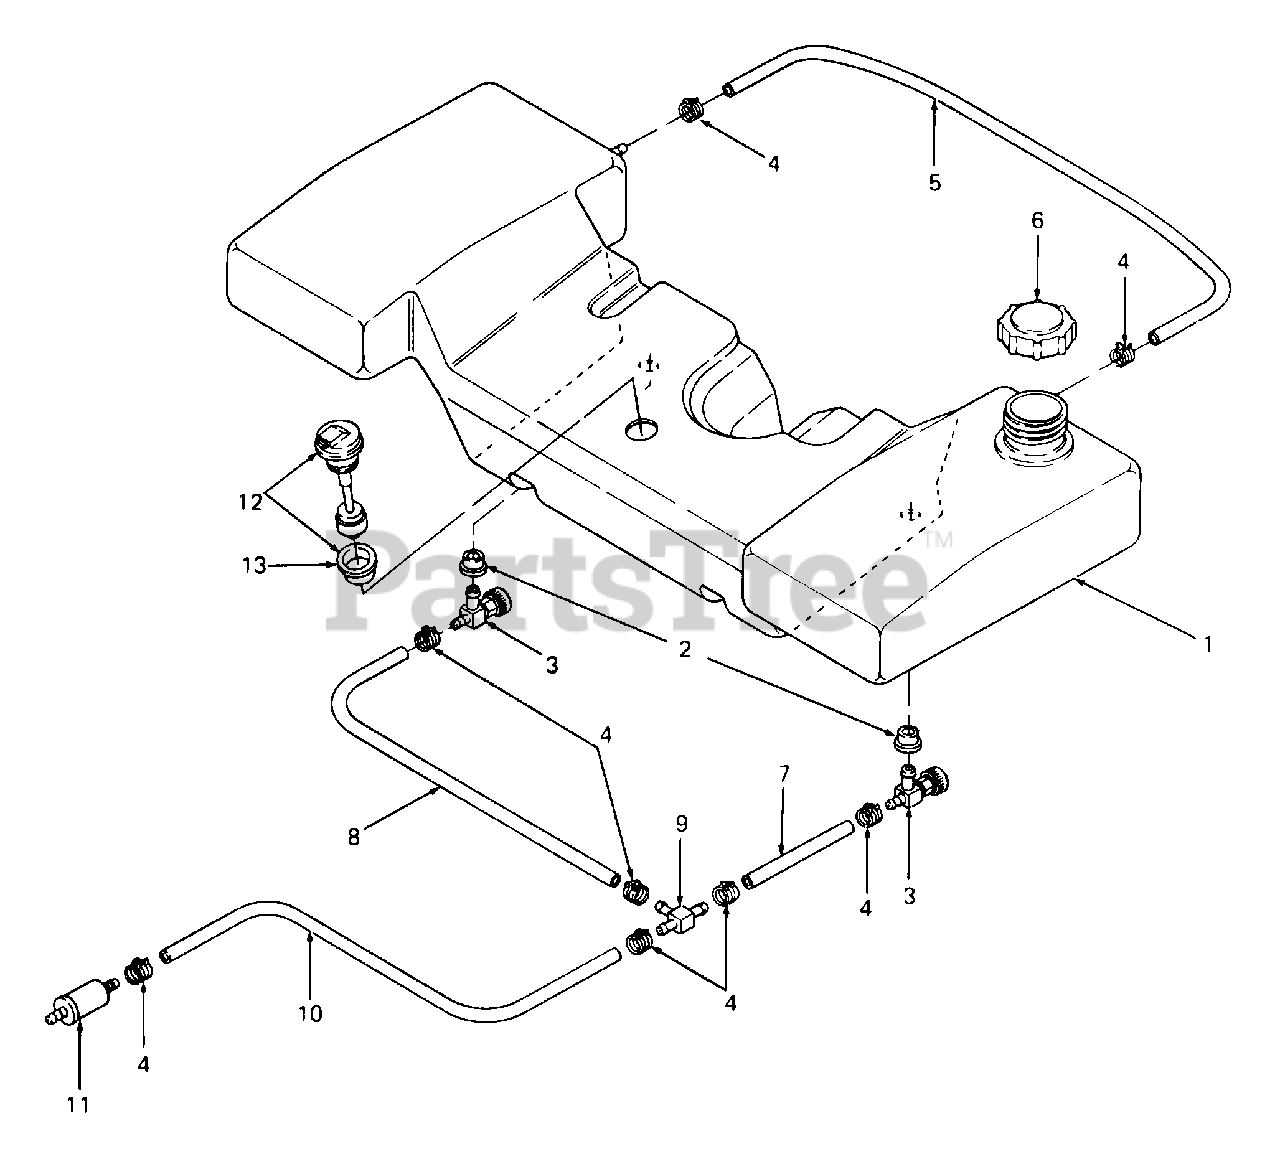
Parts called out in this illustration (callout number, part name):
1	Tank, Fuel
2	Bushing
3	Valve, Fuel Shutoff
4	Clamp, Hose
5	Line, Fuel-24" Lg
6	Cap, Fuel
7	Line, Fuel-5" Lg
8	Line, Fuel-17" Lg
9	T-Fitting
10	Line, Fuel-41" Lg
11	Filter, Fuel
12	Sensor, Low Fuel
13	Bushing, Rubber
